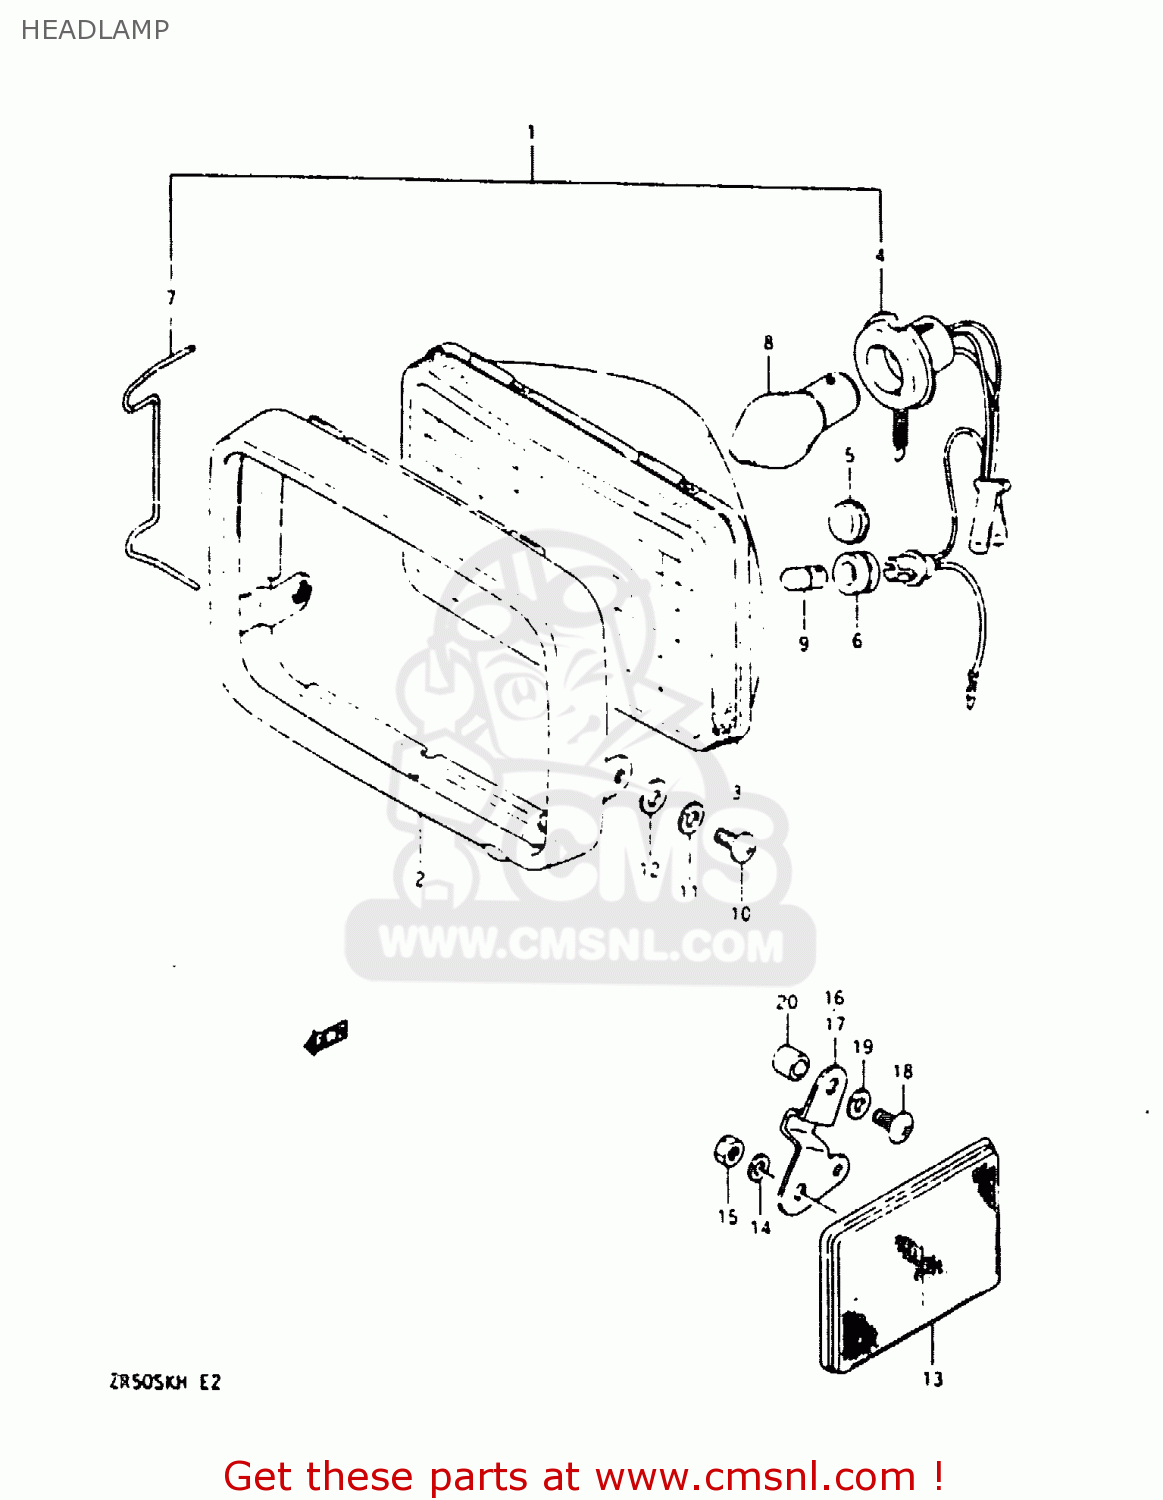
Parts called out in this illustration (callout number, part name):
1	HEADLAMP ASSY
2	RIM
3	UNIT
4	SOCKET
5	CAP
6	JOINT,RUBBER
7	SPRING
8	BULB (6V,25/25W)
9	BULB (6V,4W)
10	SCREW
11	LOCK WASHER
12	WASHER
13	REFLEX REFLECTOR
14	WASHER,LOCK
15	NUT ,5MM
16	BRACKET, RH
17	BRACKET, LH
18	SCREW
19	WASHER,5MM
20	SPACER (5.5X9.5X6.5)
